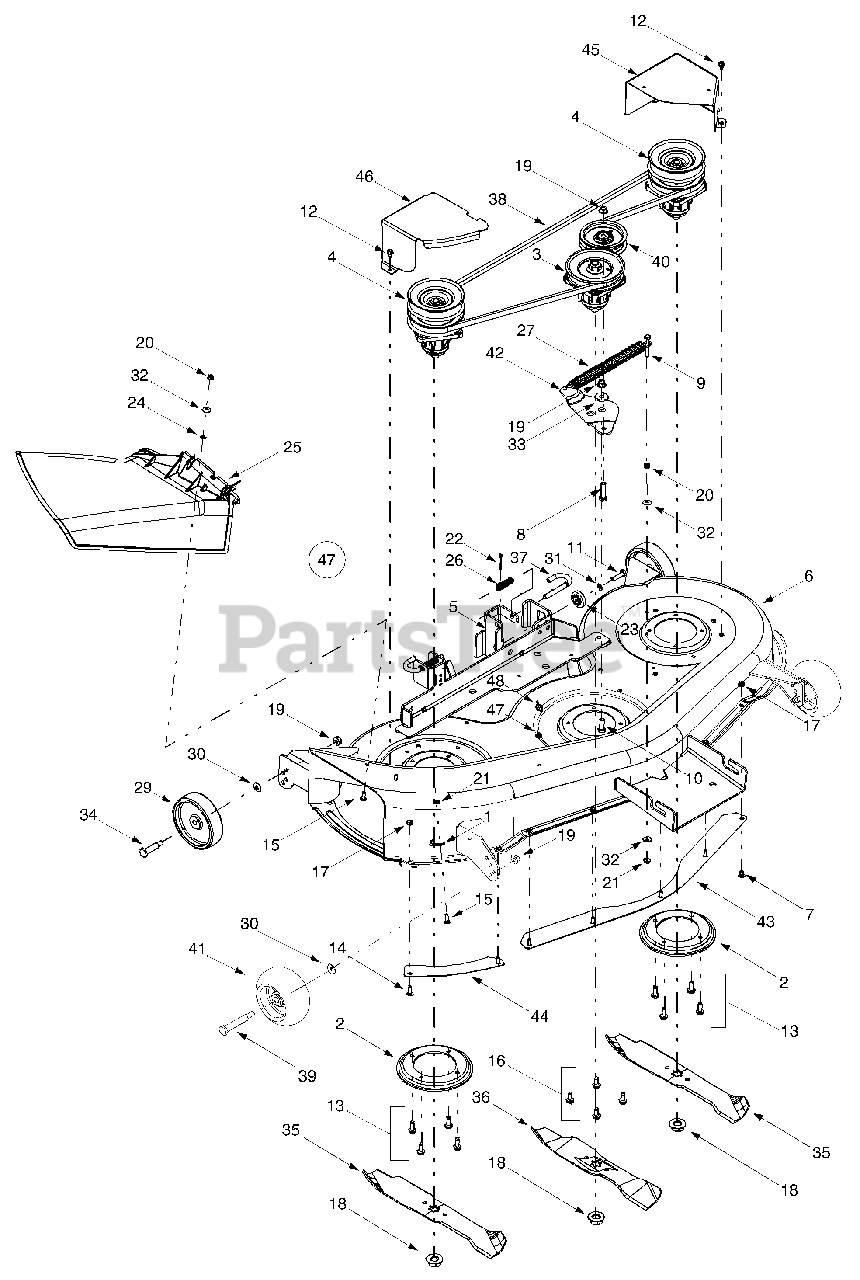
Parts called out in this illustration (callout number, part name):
1	Retainer Hook
4	Double Pulley Spindle Assembly
8	Hex Cap Screw, 3/8-16 x 1.5
9	Hex Cap Screw, 1/4-20 x 2.0
10	Hex Cap Screw, 3/8-16 x 1.0
11	Hex Cap Screw, 5/8-18 x 1.25
12	Self-tapping Screw,1/4-20 x .5
13	Self-tapping Screw,15/16-18 x .875
14	Hex Screw, 1/4-20 x .75
15	Hex Cap Screw, 1/4-20 x .62
16	Self-tapping Screw, 5/16-18 x .75
17	Hex Sems Nut, 1/4-20
18	Hex Flange Nut, 5/8-18
19	Flange Lock Nut, 3/8-16
20	Hex Nut, 1/4-20
21	Hex Flange Lock Nut, 1/4-20
22	Cotter Pin, 1/8 x 1.25
23	Deck Adjustment Gear
24	Push Nut. .25 x .5
25	Side Discharge Chute Assembly
26	Compression Spring, .406 x .531 x 1.75
27	Extension Spring, .91 x 7.3
29	Deck Wheel, 5 x 1.38
30	Bell Washer, .401 x .87 x .063
31	Lock Washer, 5/16
32	Bell Washer, .265 x .75 x .062
33	Shoulder Spacer, .625 x 1.16
34	Shoulder Screw
35	Three-in-one Blade, Star Center, 16.28"
36	Three-in-one Blade, Star Center, 14.88"
37	Deck Release Pin
38	Deck Belt, Poly
39	Shoulder Screw, 1/2-2.5
40	Idler Pulley, 3.5
41	Deck Wheel, 5.0
